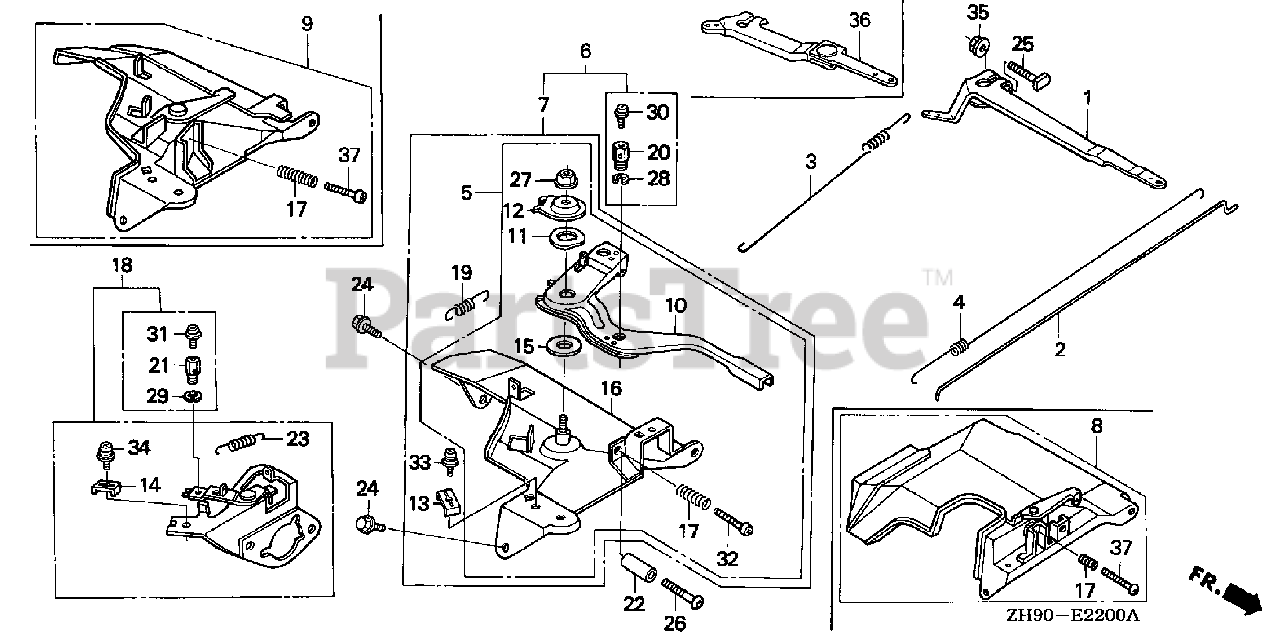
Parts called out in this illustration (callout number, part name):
2	ROD, GOVERNOR
3	SPRING, GOVERNOR
4	SPRING, THROTTLE RETURN
9	CONTROL ASSY.
17	SPRING, CONTROL ADJUSTING
24	BOLT, FLANGE (6X12) (CT200)
25	BOLT, GOVERNOR ARM
35	NUT, FLANGE (6MM)
36	ARM, GOVERNOR
37	SCREW, PAN (5X35)
